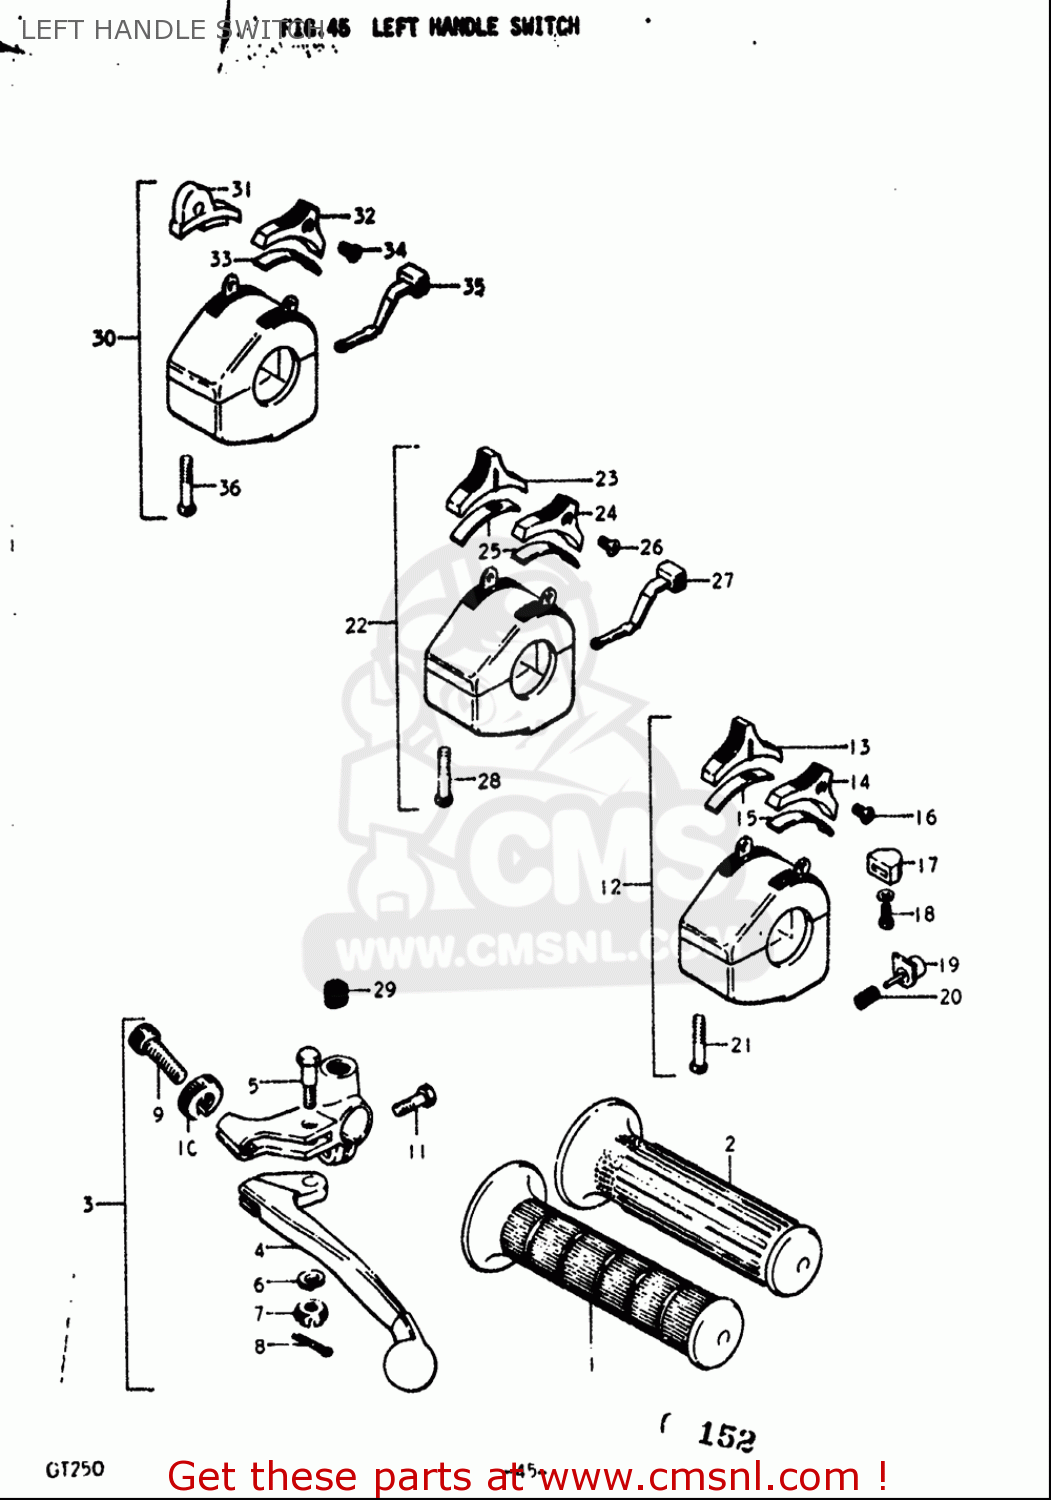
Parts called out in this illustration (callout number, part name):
1	GRIP,L
2	GRIP,L
3	LEVER ASSY,CLUTCH
4	LEVER,CLUTCH
5	BOLT,LEVER PIVOT
6	WASHER,LOCK
7	NUT,LEVER FITTNG
8	PIN 16X20
9	ADJUSTER,CABLE
10	NUT,CABLE ADJUSTER
11	BOLT
13	KNOB,HANDLE SWITCH
14	KNOB
15	PLATE,SWITCH KNOB
16	SCREW
18	SCREW
19	BUTTON,HORN
20	SPRING,BUTTON
21	SCREW
23	KNOB,HANDLE SWITCH
24	KNOB
25	PLATE,SWITCH KNOB
26	SCREW
28	SCREW
32	KNOB
33	PLATE,SWITCH KNOB
34	SCREW
36	SCREW
